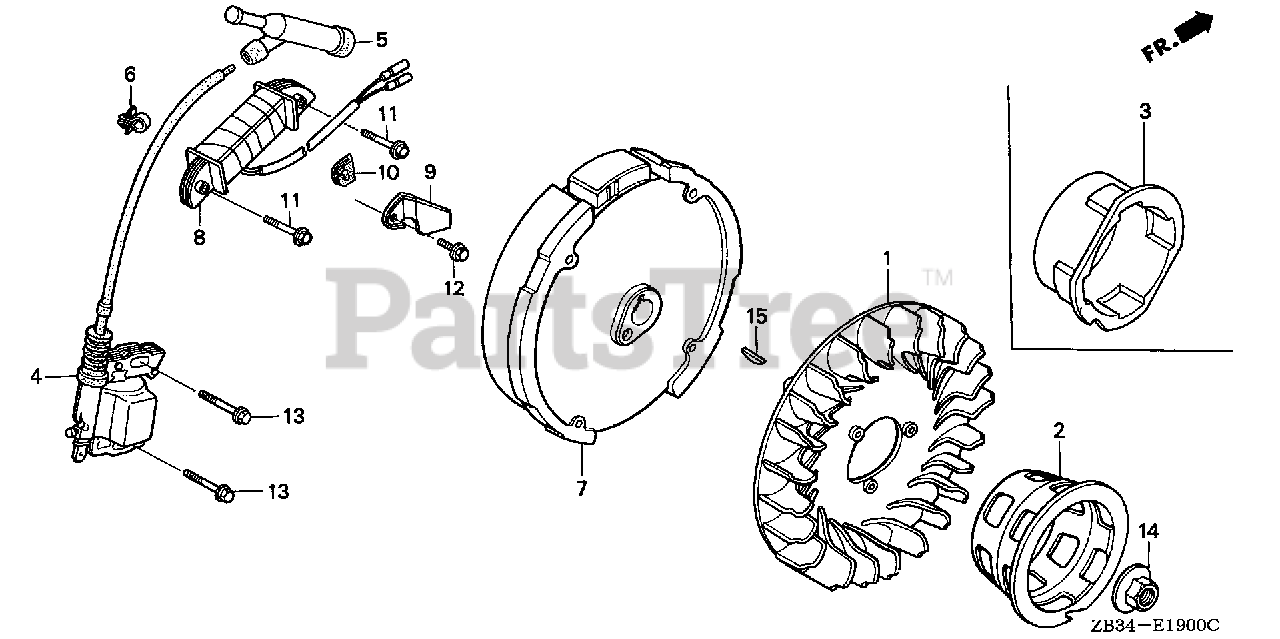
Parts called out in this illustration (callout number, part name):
1	FAN, COOLING
3	PULLEY, STARTER
4	COIL ASSY., IGNITION
5	CAP ASSY., NOISE SUPPRESSOR (NICHIWA Y-EZ RTFM256)
7	FLYWHEEL (LAMP)
8	COIL ASSY., BACK-UP
9	CLAMP, WIRE
10	GROMMET, WIRE
11	BOLT, FLANGE (6X28) (CT200)
12	BOLT, FLANGE (5X10)
13	BOLT, FLANGE (6X25) (CT200)
14	NUT, SPECIAL (14MM)
15	KEY, SPECIAL WOODRUFF (25X18)
